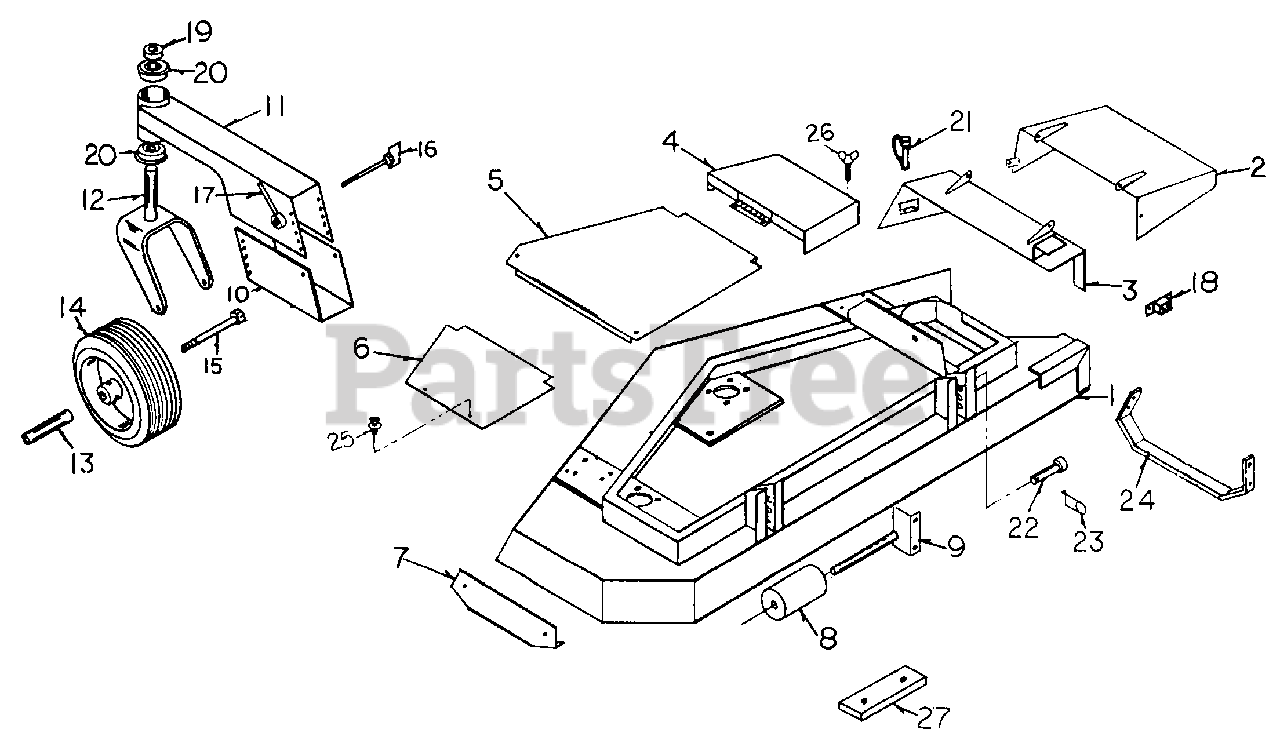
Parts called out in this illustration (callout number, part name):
1	Deck, 62"
3	Foot Guard Mount
8	Anti-scalp Roller
9	Shaft & Bracket
10	Gauge Wheel Mount Bracket
11	Gauge Wheel Mount
13	Axle
14	Gauge Wheel Assembly
18	10 Amp Circuit Breaker
19	Set Collar, 1"
23	Hair Pin Cotter
24	Shoe, RH
25	Thumb Screw, 1/4-20 x 1/2"
26	Wing Screw, 1/4-20 x 1"
27	Tail Weight, 13 Lb.
